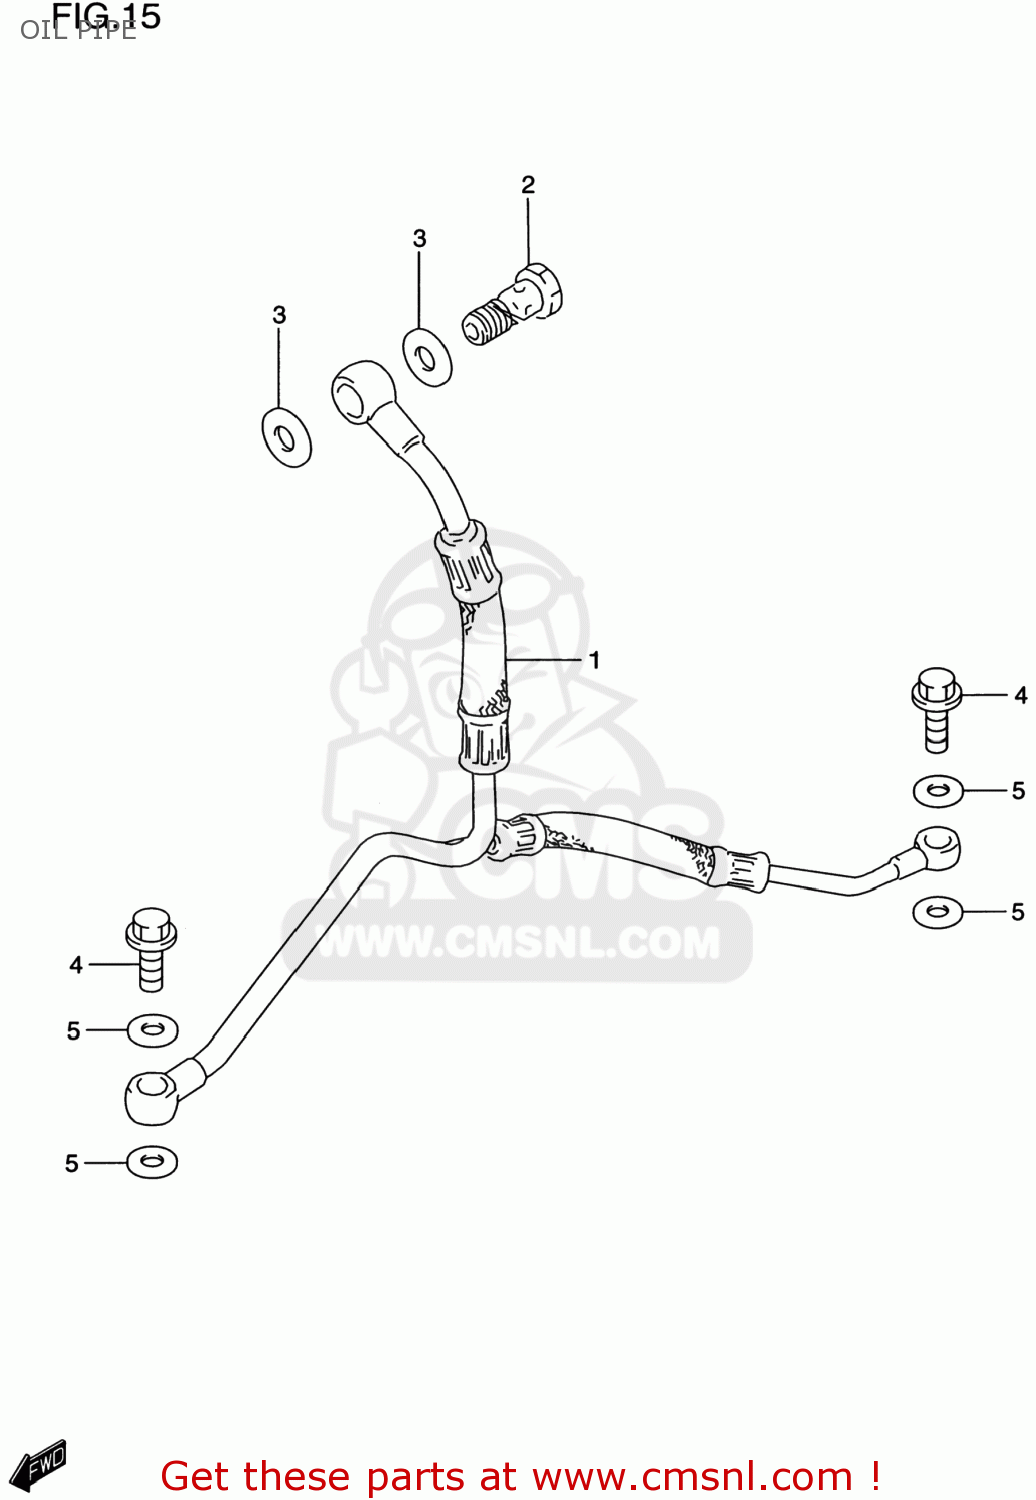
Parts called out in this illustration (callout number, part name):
1	PIPE,T/M & CSHAFT OIL
2	BOLT UNION
3	GASKET(12X17X1) (NAS)
4	BOLT UNION
5	GASKET(10.1X16X1) (NAS)
